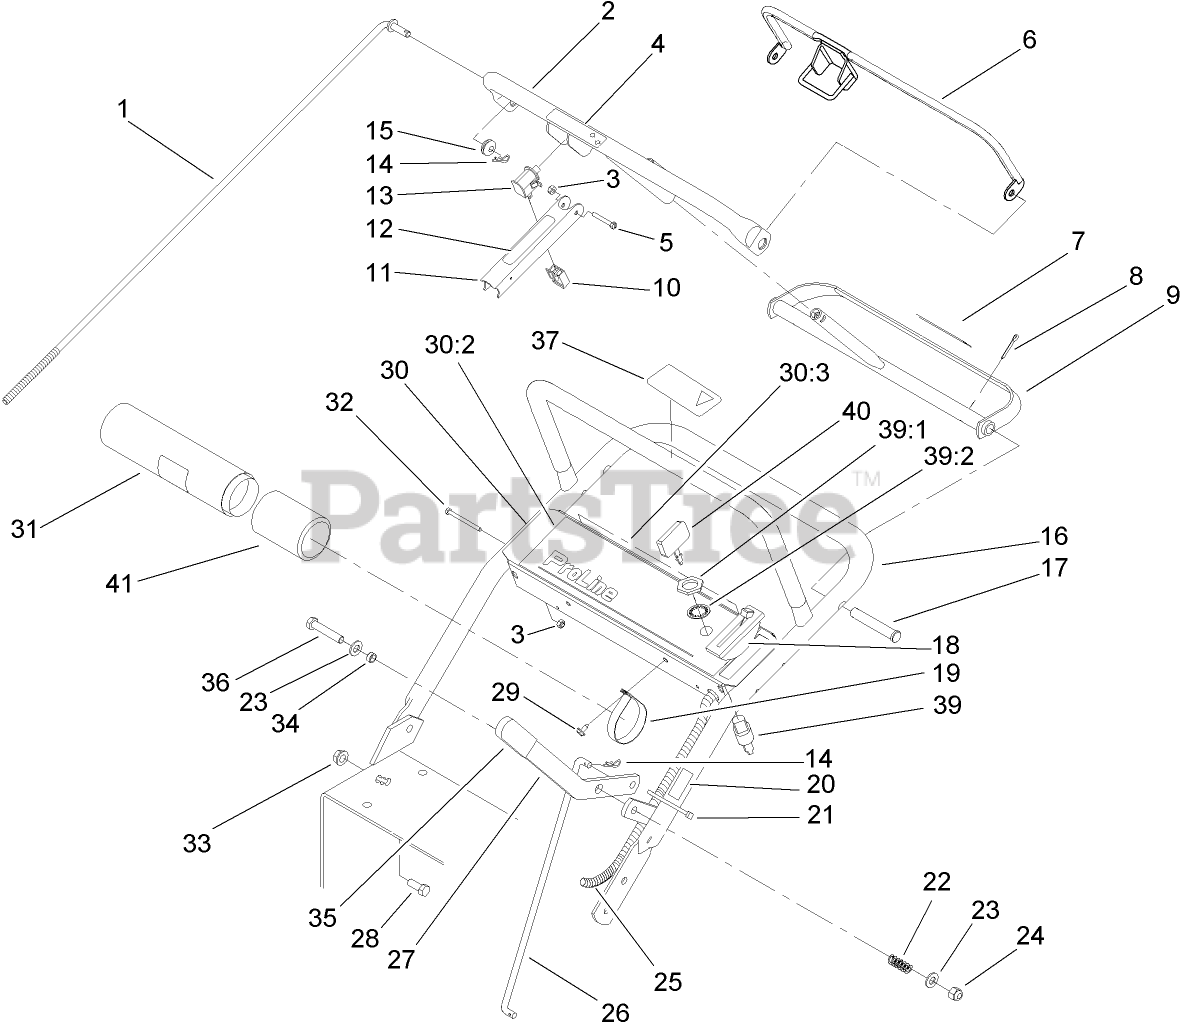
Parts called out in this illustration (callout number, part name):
1	ROD-CONTROL
2	BAR-CONTROL
3	NUT-LOCK, NI
4	DECAL
5	SCREW-SHH
7	DECAL
8	PIN-COTTER
9	CONTROL-PIVOT
10	CONNECTOR-BODY
11	LEVER-BRAKE, PARKING
12	DECAL
13	SWITCH
14	PIN-COTTER
15	GROMMET-RUBBER
16	HANDLE-UPPER
17	PIN-CLEVIS
18	CONTROL-THROTTLE
19	CLAMP-R
20	DECAL-ENGAGE, DECK
21	TIE-PLASTIC
22	SPRING-COMPRESSION
23	WASHER-FLAT
24	NUT-LOCK, NI
25	Harness-Wire
26	LINKAGE-DRIVE, BLADE
27	LEVER-ENGAGEMENT, BLADE
28	SCREW-HHF
29	SCREW-HWHTF
30	CONTROL PANEL ASM
30:2	DECAL-PANEL, CONTROL
30:3	DECAL-DANGER
31	TUBE-MANUAL
32	SCREW-SHH
33	NUT-HF
34	SPACER
35	GRIP-LEVER
36	SCREW-HH
37	DECAL-PROTECTION, EAR
39	SWITCH-ON / OFF
39:1	NUT-HH
39:2	WASHER-TOOTH, INTERNAL
40	KEY-IGNITION
41	CAP-HOUSING
